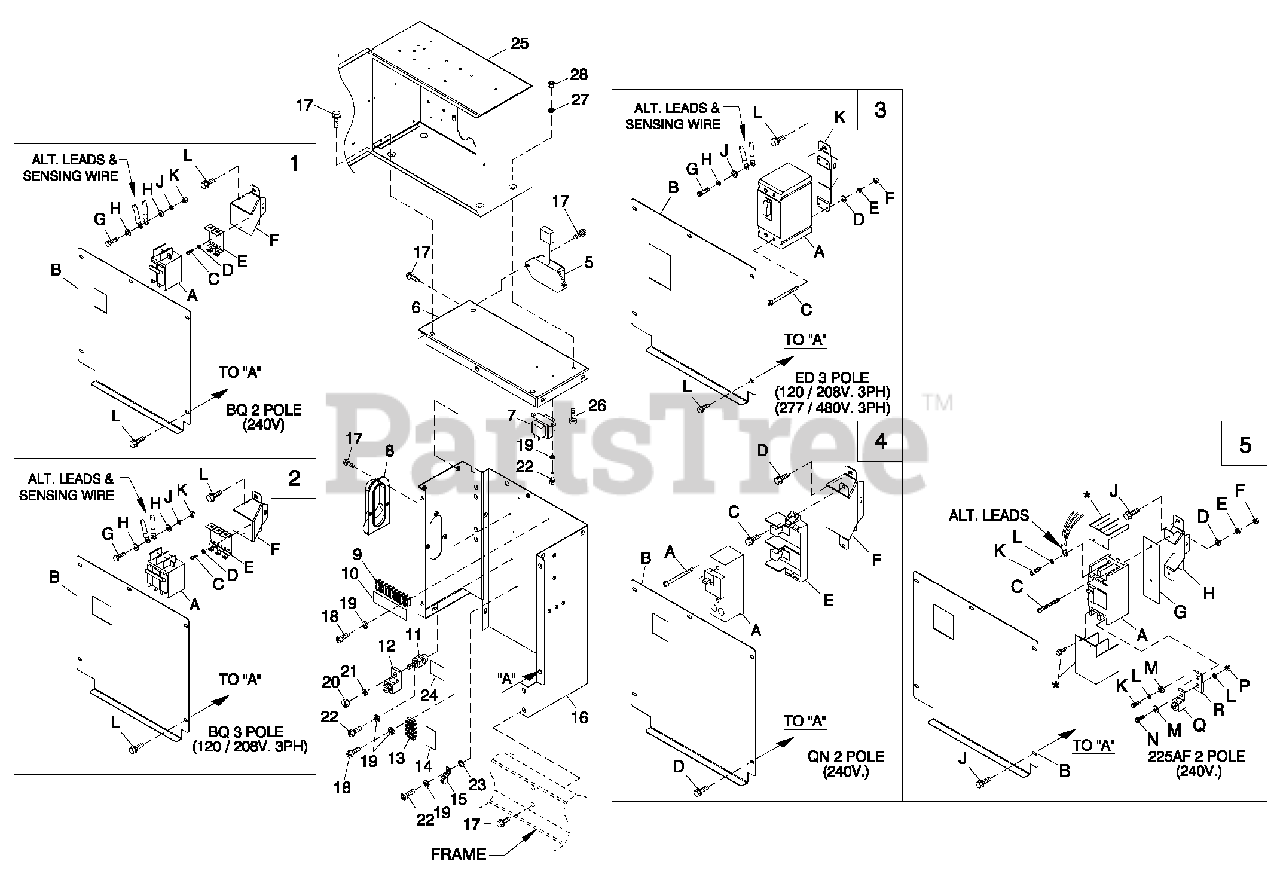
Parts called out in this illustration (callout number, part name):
3	UL BREAKER ED
4	UL BREAKER QN
5	REGULATOR-DC ALT
5	ULBREAKER
6	CONBOX TOP PANEL SUPPORT
7	XFMR208TO 16V 6VA(208V. ONLY)
8	COVER BELL HOUSING CONBOX
9	BLOCK TERM 20A 8 X 6 X 1100V
10	DECAL UTIL SENSE/CUST CONN
11	JUNCTION BLOCK 3/8-16
12	LUG SLDLSS 350-#6X13/32 AL/CU
13	BLOCK TERM 20A 6 X 3 X 1100V
14	DECAL CUST CONN 120V UTILITY
15	LUG SLDLSS #6-14X 13/64 CU
16	CONBOX BACK & SIDES 1.6L
17	SCREW HW HTF M6-1.0X16
18	SCREW P HTTM4-0.7X16ZYC
19	WAS HER LOCK #8-M4
20	NUT HEX 3/8-16 STEEL
21	WAS HER LOCK 3/8
22	SCREW P HTTM4-0.7X12ZYC
23	WAS HERS HAKEPROOF EXT#10STL
24	DECAL NEUTRAL
25	ASSY R-200 3600 1.6L
26	SCREW H HC M6-1.0X 16G8.8
27	WAS HER LOCK M6-1/4
28	NUT HEXM6X1.0G8YELCHR
A	CB0090A2P 240V SBQ2 LL
B	CB COVER 20-25K1P(BQ2)
C	SCREW P HTT M4-0.7X12ZYC
D	WAS HER LOCK #8-M4
E	BRKT CB MTG BACK
F	CIRCUIT BREAKER SUPPORT (BQ)
G	SCREW H HC M5-0.8X 20 G8.8
H	WAS HER FLAT #10 ZINC
J	WAS HER LOCK M5
K	NUT HEX M5-0.8 G8 CLEAR ZINC
L	SCREW HW HTF M6-1.0X 16
A	CB0070A3P 240V SBQ3 LL
B	CB COVER 20-25K3P (BQ3)
C	SCREW P HTT M4-0.7 X 12ZYC
A	CB0030A3P 480V SED 4 LL
B	CB COVER 20-30K3P (ED)
C	SCREW R HM #8-32X4-1/2
D	WAS HER FLAT #8 ZINC
E	WAS HER LOCK #8-M4
F	NUT HEX #8-32 STEEL
G	SCREW S H C 1/4-28 X 3/4 G8.8 NZ
H	WAS HER LOCK M6-1/4
J	WAS HER-STEP 1/2ODX9/32ID BRASS
K	CIRCUIT BREAKER SUPPORT (ED)
L	SCREW HW HTF M6-1.0X16
A	CB0150A2P 240V SQN2 LL
B	CONBOX FRONT COVER 1.6L QN 2P
C	SCREW H HTT M5-0.8X 10 BP
D	SCREW HW HTF M6-1.0X16
E	BASE, QN CIRCUIT BREAKER
F	BREAKER SUPPORT BRACKET 30KW
A	CB 150A2 POLE 240V 225AF
B	CB COVER 30KG 225AF
C	SCREW R HM #8-32X3-1/4
G	INSULATOR CB 2P 225AF
H	CIRCUIT BREAKER SPPRT G 225AF
J	SCREW HW HTF M6-1.0X16
K	SCREWS H C M8-1.25X20G8
L	WAS HER LOCK M8-5/16
M	WAS HER FLAT 5/16-M8 ZINC
N	SCREW S H C M8-1.25 X 25 G12.9
P	NUT HEX M8-1.25 G8 CLEARZINC
Q	LUG SLDLSS 300 MCM-6 AL/CU
R	BUS BAR 200A LUG ADAPTOR
